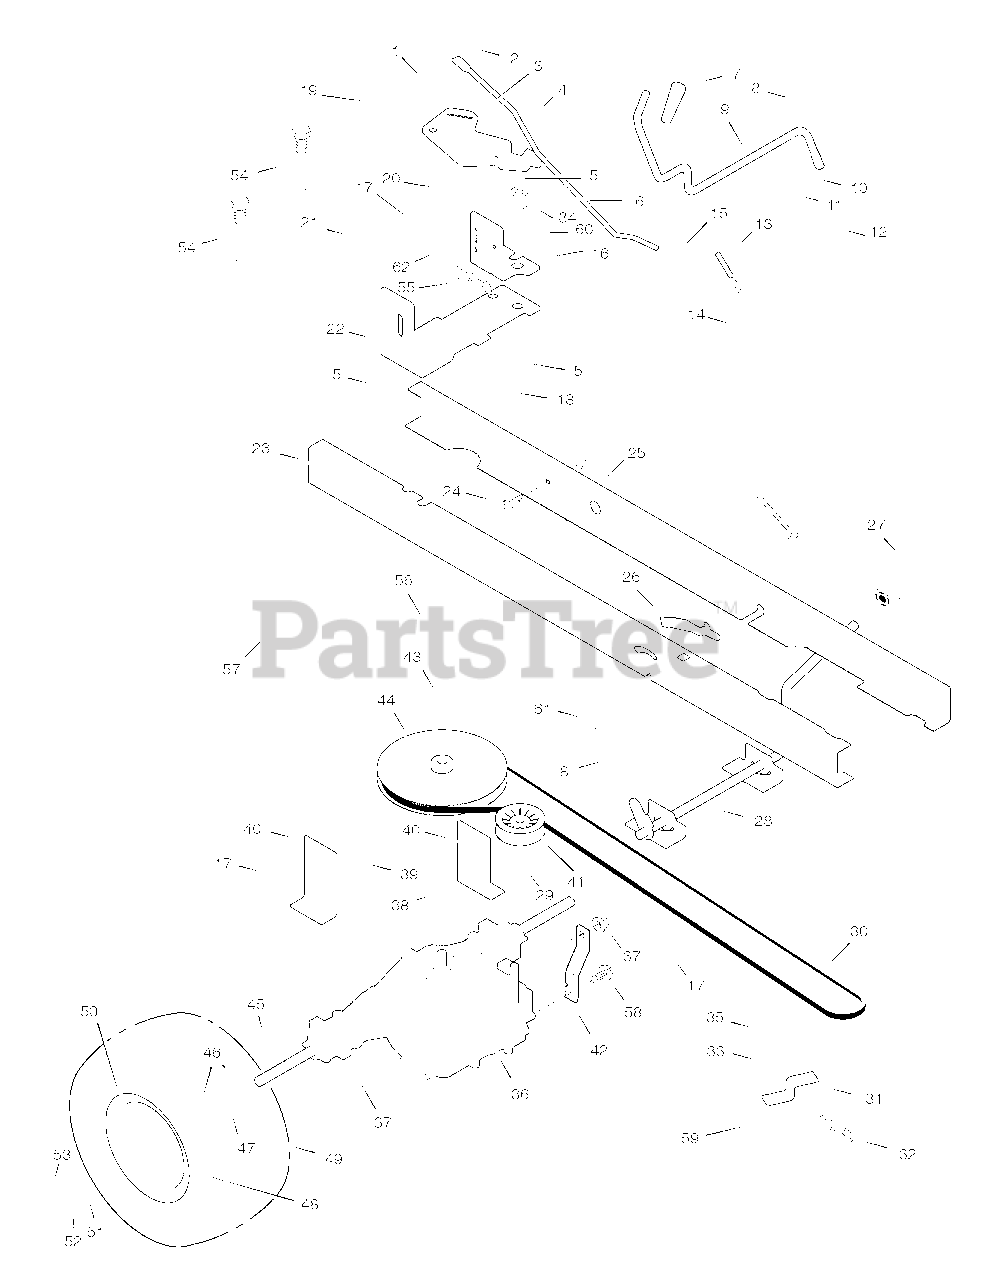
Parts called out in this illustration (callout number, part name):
1	Bolt, Shoulder
2	Nut, Hex
3	ARM, Idler
4	Rod, Clutch
5	Nut
6	Washer
7	Grip
8	Pin, Cotter
9	Lever, Shift
10	Washer
11	Link, Shift
12	Nut, Adjuster
14	Rod, Parking Brake
15	Nut, Adjuster
16	Bracket, Shift Pivot
18	Nut
19	Mount, Stud Spring
20	Bolt, Shoulder
21	Spring, Extension
22	Bracket, Right Shifter
23	Frame, Right
24	Bolt, Carriage
25	Frame, Left
26	Latch, Parking Brake
27	Pedal
28	Lever, Brake/Clutch
29	Nut
30	Belt, Motion Drive
31	Yoke, Shift
32	Pin, Hair
36	Transaxle, Peerless **
37	Nut
38	Key, Woodruff
39	Bolt
40	Bracket, Transaxle
42	BRACKET, Torque Strap, LH
43	Ring, Retainer Snap
44	Pulley, Drive
45	Key, Square
47	Spacer, Transaxle
48	Stem, Valve
50	Wheel & Tire Assembly
53	Hub Cap
54	Guide, Belt
55	Pin, Hair
56	Spring, Extension
57	Spring, Extension
61	Washer
